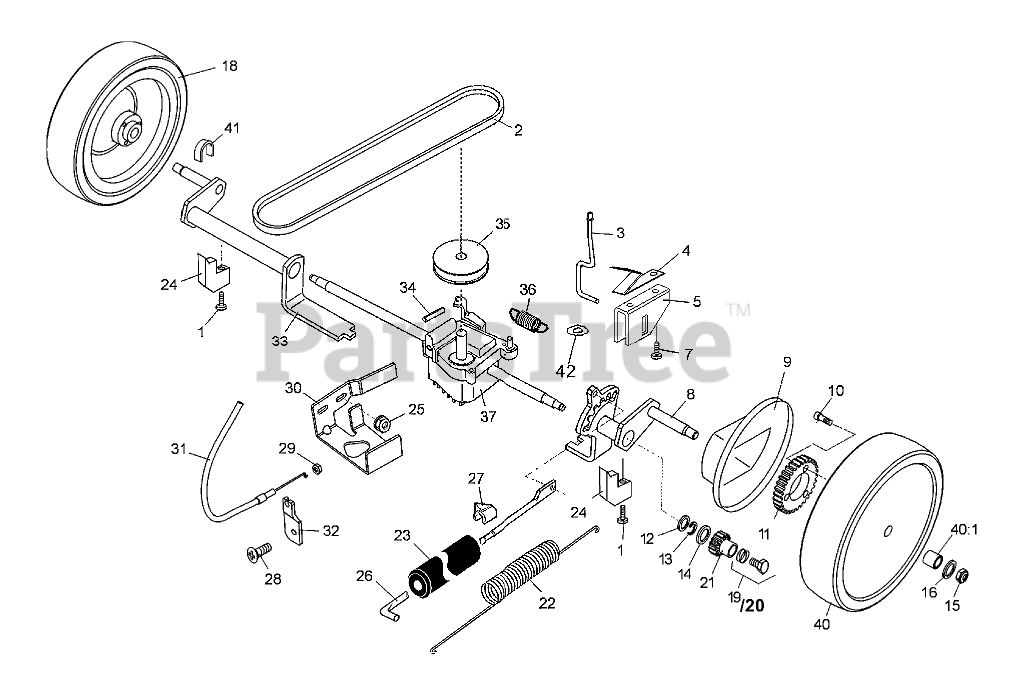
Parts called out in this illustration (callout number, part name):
1	SCREW-RETAINER
2	BELT - V
3	ROD-TRIGGER
4	SPRING-RETURN, TRIGGER
5	SADDLE-HEIGHT OF CUT
7	SCREW-RH
8	AXLE - REAR
9	COVER-WHEEL
10	Screw-Wheel Gear
11	GEAR-WHEEL
12	WASHER-COVER
13	WASHER-AXLE
14	WASHER-GEAR
15	NUT-HH
16	WASHER-GEAR
18	Wheel-Rear (incl. Ref. 40:1)
19	LEFT BUSHING ASM
20	RIGHT BUSHING ASM
22	SPRING-COUNTERBALANCE
23	COVER-SPRING
24	RETAINER-AXLE
26	ROD-LINK
27	INDICATOR-HEIGHT OF CUT
28	SCREW-BRACKET
29	Nut-Cable
30	Guide-Belt
31	Cable-Drive (incl. Ref. 29)
32	Retainer-Cable
33	AXLE - REAR
34	Pin-Roll
35	PULLEY-GEARBOX
36	Spring-Clutch
37	Gearbox Ass. (Incl. Ref # 34+35)
40	Wheel-Rear (incl. SmartWheel)
40:1	BUSHING
41	CAP-AXLE, REAR
42	Washer
